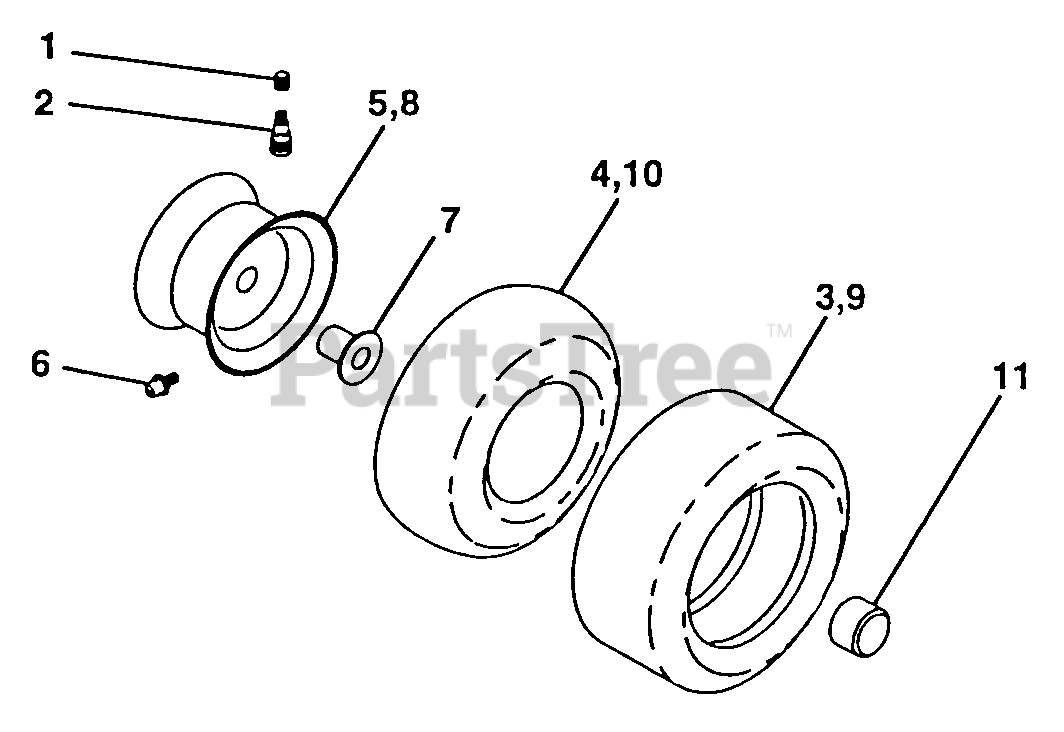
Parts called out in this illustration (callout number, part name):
1	Cap Valve Tire
2	Stem Valve
3	Tire F Ts 15 X 6 0 - 6 Service (AYP part number)
4	Tube Front
5	Rim Asm 6" front Silver Service
6	Fitting Grease
7	Bearing Flange
8	Rim Asm 8" rear Silver Service
9	Tire R Ts 18 x 9 5 -8 C Service (AYP part number)
10	Tube Rear
11	Cap Axle Blk 1 50 X 1 00 (AYP part number)
